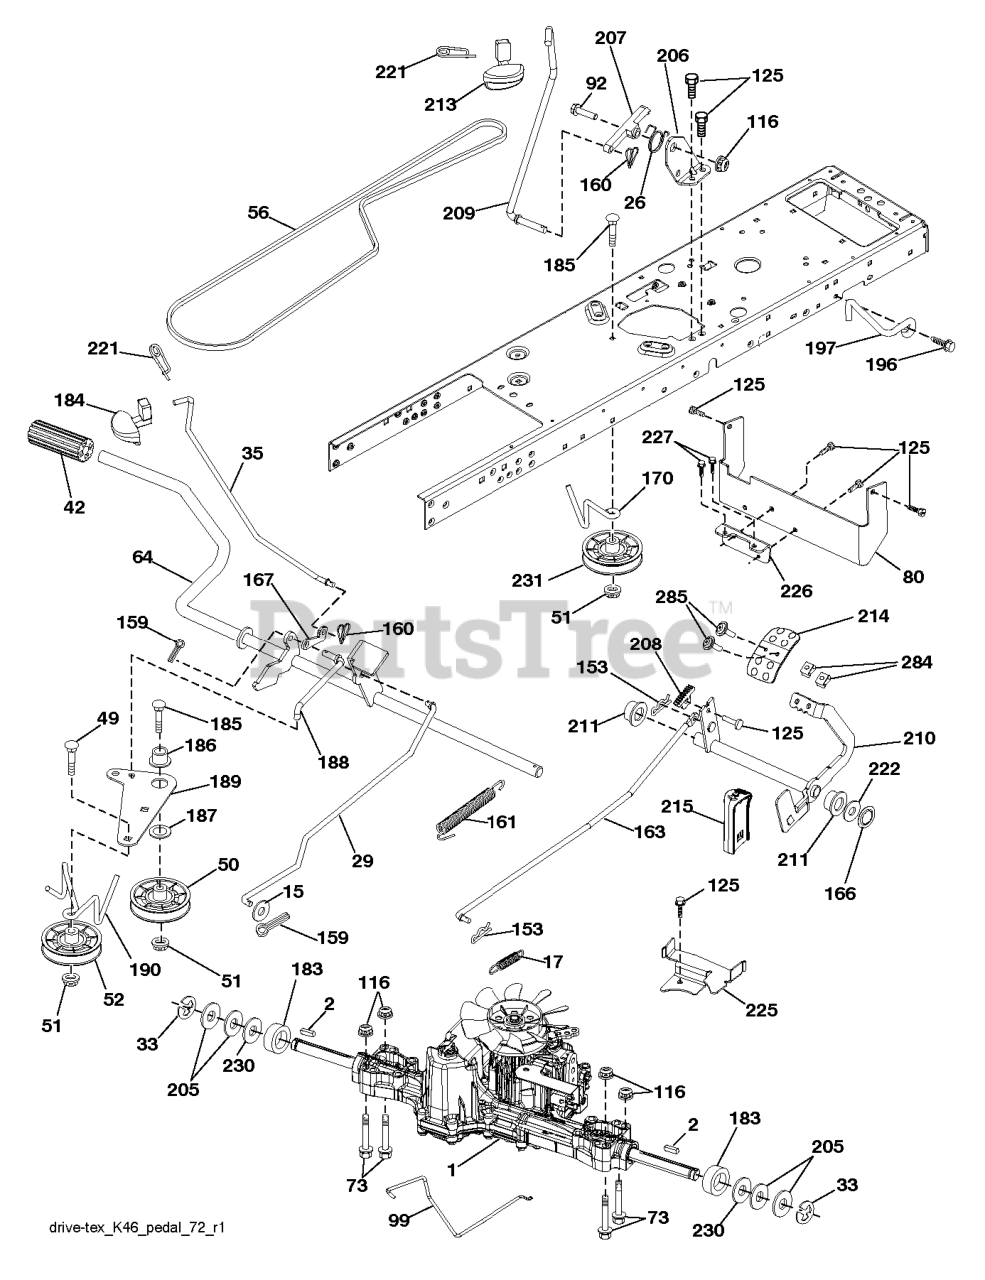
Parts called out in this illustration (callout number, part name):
1	TRANSAXLE(K46BT).PDL.
2	SQUARE KEY
15	WASHER
17	SPRING.BRAKE.K46.GREEN
26	SPRING.RETURN.CRUISE
29	ROD.BRAKE.K46
35	ROD.BRAKE.PARTK.HUSQ.TEX
42	PEDAL COVER T
50	IDLER.FLAT.910.OFFSET
51	NUT LOCK FLG 3/8-16 UNC
52	IDLER.V-GROOVE.910.OFFSET
56	V-BELT.MOWER.92.40.42/K46
64	SHAFT.ASM.PEDAL.BRK.CNTR
73	BOLT
80	STRAP.TORQUE.K46.K57R.TT
92	BOLT
99	ROD.SPRING.BYPASS.K46.LT.Z
116	NUT LOCK HEX FLANGE 5/16-18
125	SCREW
153	RETAINER M
159	COTTER PIN
160	RETAINER CLIP
161	SPRING, RETURN LT
163	ROD.CONTROL.PEDAL.K46
166	NUT.PUSH.625
167	LATCH.BRAKE.SPRING
170	KEEPER.V-IDLER.CENTER.
183	SPACER AXLE
184	RB HANDLE.PARKG.BRK.HUS/PRED
186	SPACER.RETAINER
187	WASHER 12/32X2X10GA
188	RP.LINK.CLUTCH.GROUND.DRIVE
189	BELLCRANK.GROUND.DRIVE.TEX.
190	KEEPER.BELLCRANK.DRIVE
196	SCREW 3/8-16X1
197	LINK.CLUTCH.ANIT-ROTAT
206	BRKT.MOUNT.LATCH.CRUIS
207	LATCH.CONTROL.CRUISE
208	GEAR.SECTOR.CONTROL.CR
209	ROD.CONTROL.CRUISE.GT.
210	ROCKER.ASM.PEDAL.CONTR
211	BEARING.NYLON
213	KNOB.CONTROL.CRUSIE.HU
214	PEDAL.FORWARD.HUSQVARNA.DEALER
215	PEDAL.REVERSE.TEX.GT.4
221	RETAINER.SPRING.CLIP.H
222	WASHER 21/32 X 1-1/4 X 10 GA.
225	KEEPER.BELT.TRANSAXLE.K46
226	BRACKET.MOUNT.TORQUE.K46.TLT
227	SCREW.THDROL.5/16-18X3/4.TTY
230	WASHER.HARDENED
231	IDLER.V-GROOVE.1.688.OFFSET
284	NUT.U-CHNL.1/4-20.550DP.350PNL
285	SCREW.MACHINE.CR.1/4-20
